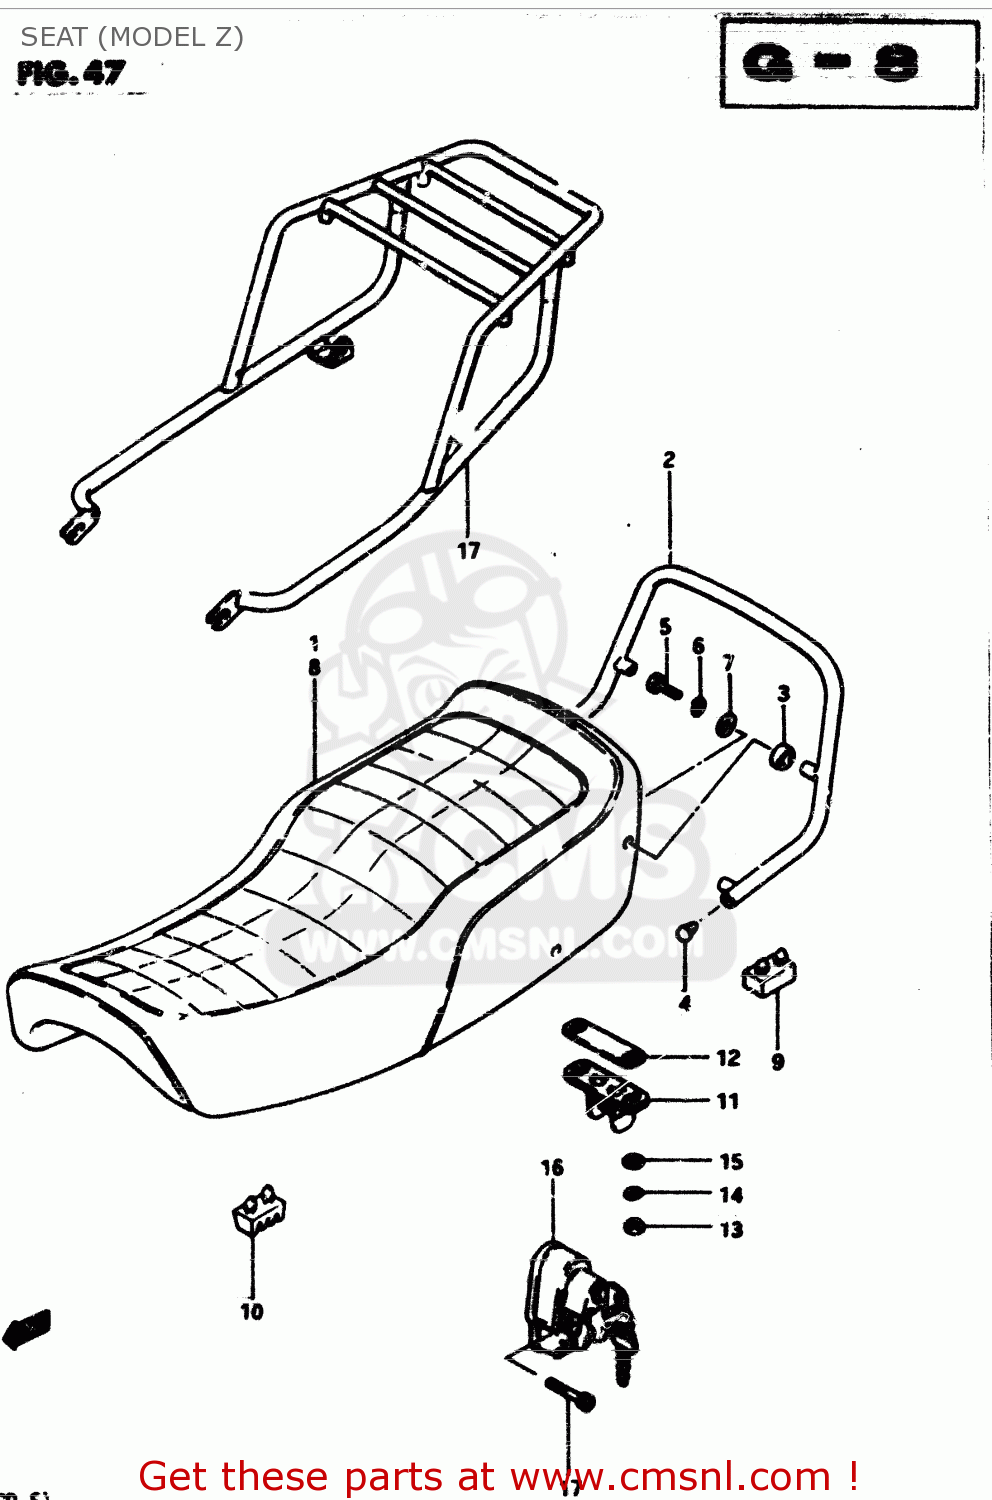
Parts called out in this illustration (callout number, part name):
1	SEAT (BLACK)
2	HANDLE,PILLION RIDER
3	CUSHION
4	END,SHEET HANDLE
5	BOLT
6	LOCK WASHER
7	WASHER
8	CUSHION
9	CUSHION,SUPPORT(50X25X32)
10	STRIKER,SEAT LOCK
11	SHIM,SEAT LOCK STRIKER
12	NUT 6MM
13	LOCK WASHER
14	WASHER
15	LOCK ASSY,HELMET
16	BOLT 5X25
17	CARRIER, SPORTS
